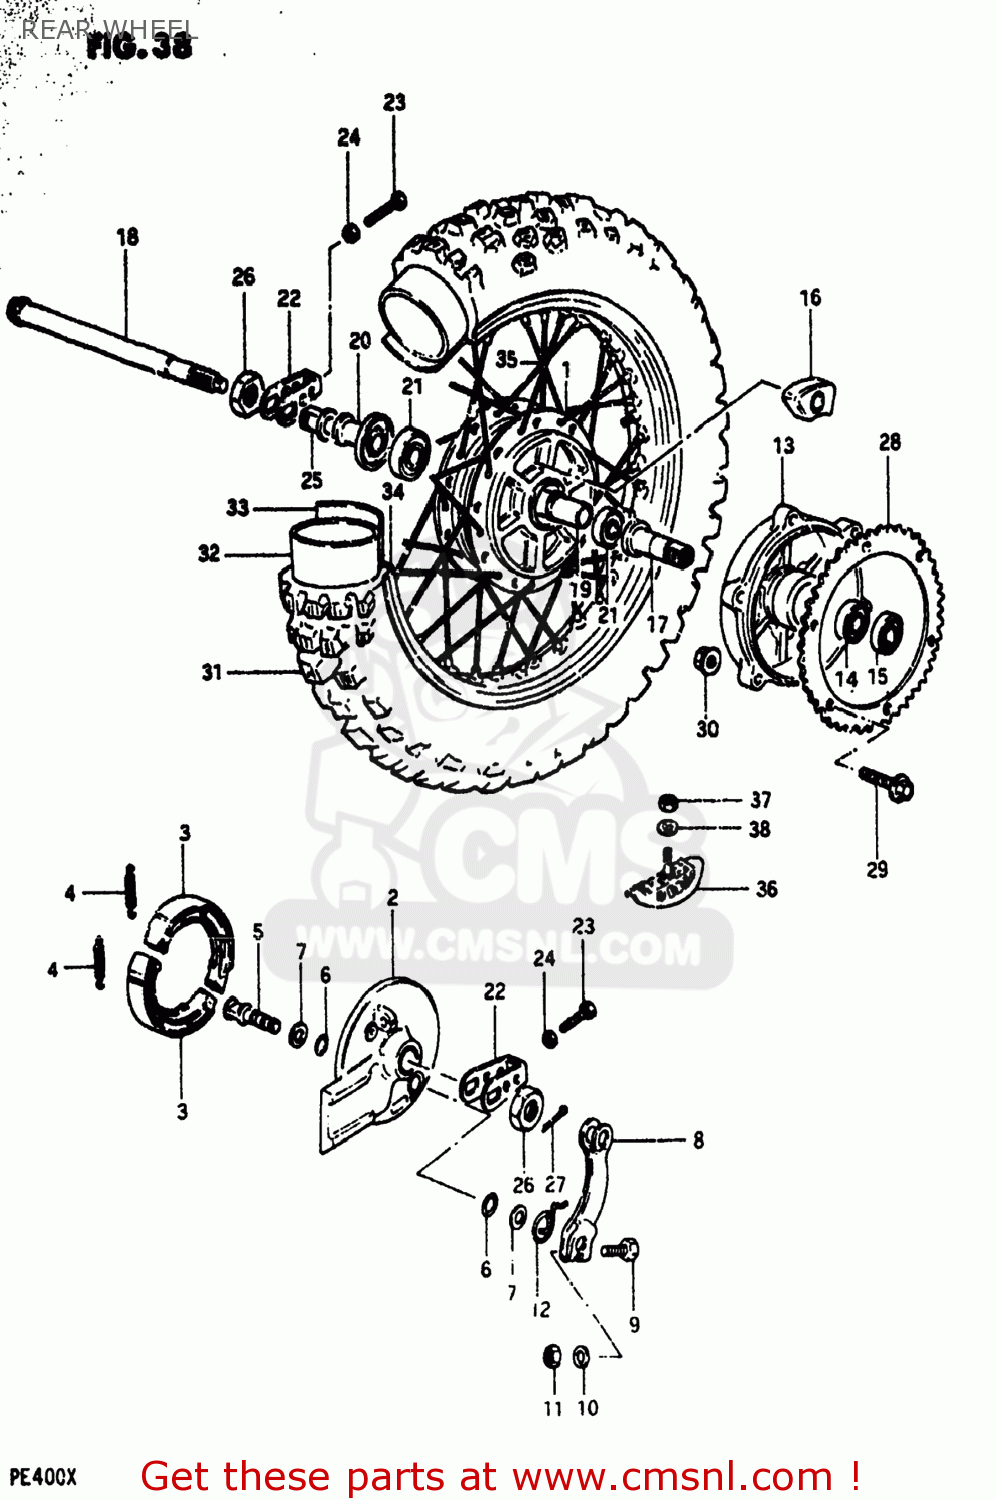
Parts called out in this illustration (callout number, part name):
1	HUB,REAR WHEEL
2	PANEL,REAR HUB
3	SHOE,BRAKE
4	SPRING
5	CAM,FRONT BRAKE
6	O-RING,BOSS
7	WASHER (15X24X1.6)
8	LEVER,REAR BRAKE CAM
9	BOLT
10	WASHER
11	NUT
12	SPRING
13	DRUM ASSEMBLY,REAR BRAKE
14	BEARING
15	BEARING
16	ABSORBER,RR HUB SHOCK
17	SHAFT,REAR BRAKE DRUM
18	AXLE,REAR
19	SPACER,REAR HUB BEARING
20	SPACER,REAR AXLE
21	BEARING
22	ADJUSTER,CHAIN
23	BOLT
24	NUT
25	SPACER,CHAIN ADJUSTER
26	NUT
27	PIN 30X20
28	SPROCKET,REAR (NT:46)(AL)
29	BOLT(8X30)
30	NUT
31	TIRE
32	TUBE,INNER
33	PROTECTOR,WHEEL,INNER
34	RIM,REAR WHEEL
35	SPOKE SET,REAR
36	STOPPER,BEAD
37	NUT
38	WASHER
